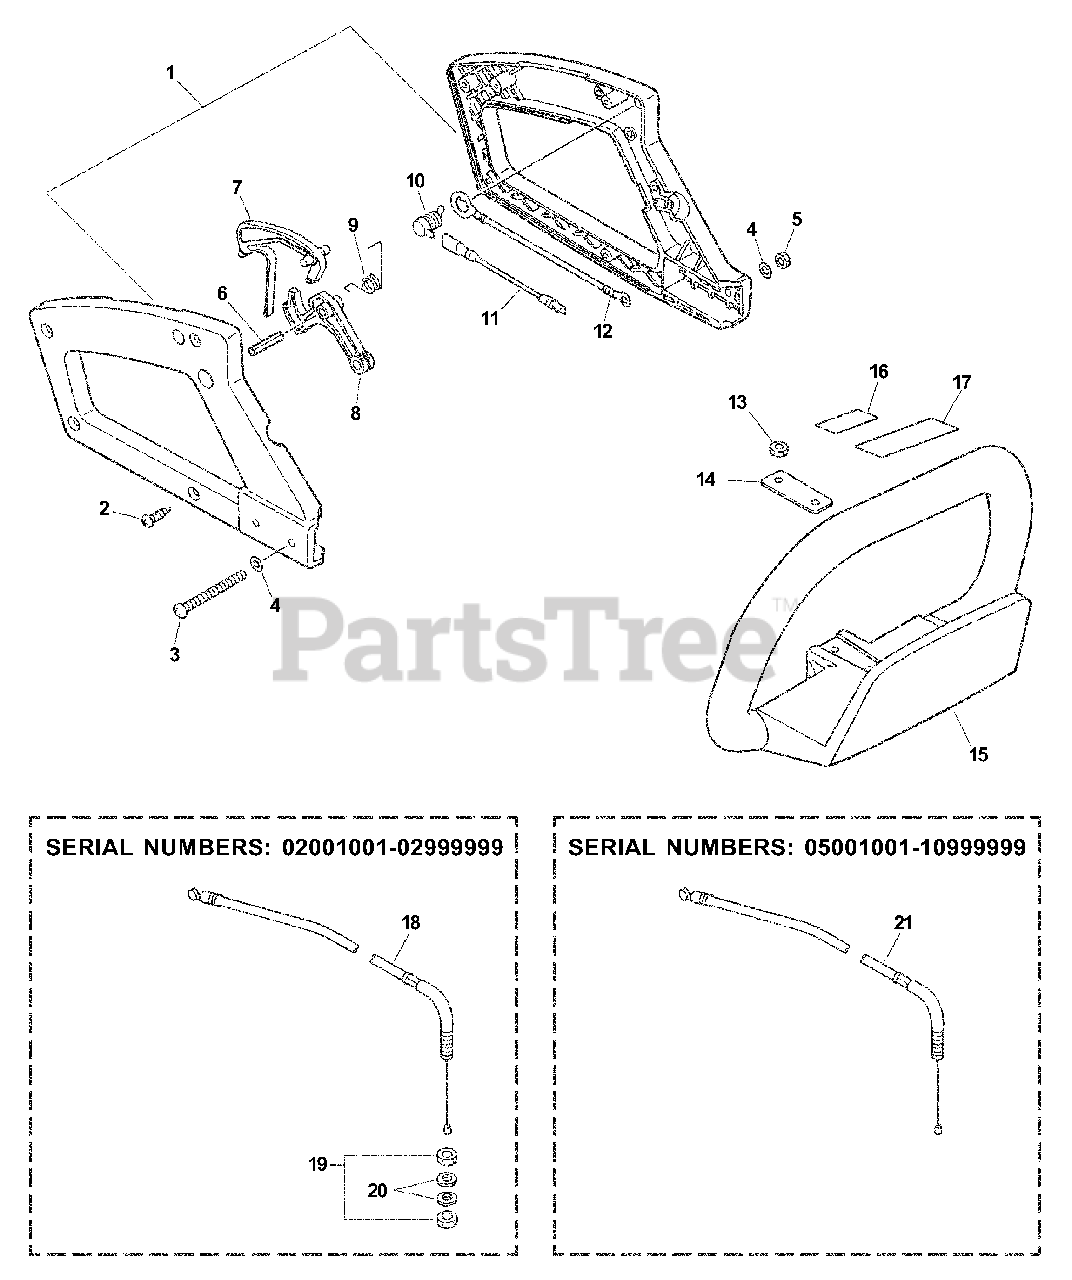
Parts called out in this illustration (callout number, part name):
1	HANDLE SET, REAR
2	SCREW 4×16
3	SCREW 5×47
4	WASHER, FLAT 5.5×10×0.8
5	NUT, LOCK M5
6	PIN, SPRING Ø5×25 MM
7	LOCKOUT, THROTTLE
8	TRIGGER, THROTTLE
9	SPRING, THROTTLE RETURN
10	SWITCH, ON-OFF
11	LEAD - IGNITION
12	LEAD - GROUND
13	NUT, LOCK M5
14	PLATE, EYE
15	HANDLE, SUPPORT
16	LABEL, CAUTION
17	LABEL, CAUTION
18	CABLE, THROTTLE
20	WASHER 6.5×11.5×0.8
21	CABLE, THROTTLE
